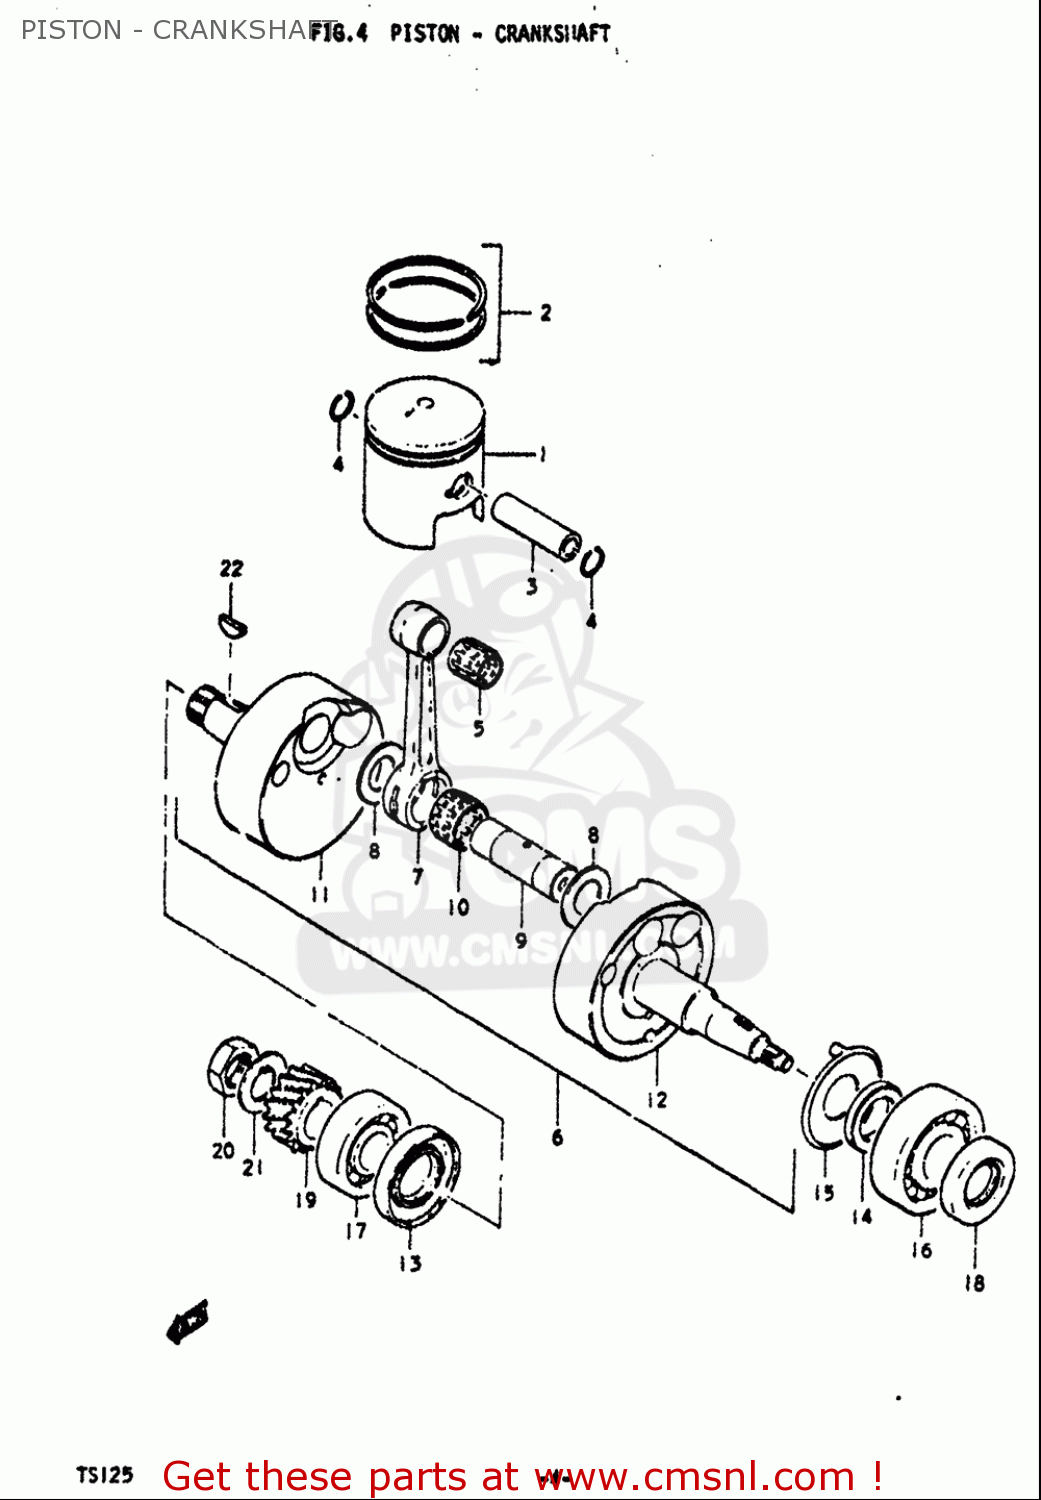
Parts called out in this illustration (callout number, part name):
1	PISTON
2	RING SET,PISTON
3	PIN ,PISTON
4	RING,SNAP 14MM
5	BEARING(14X18X19.8)
7	ROD,CONNECTING
8	WASHER(19X32X1)
9	PIN,CRANK
10	BEARING(19X25X16)
13	SEAL,OIL(26X52X8)
14	SPACER
16	BEARING(25X62X17)
17	BEARING(20X52X15)
18	SEAL,OIL(25X44X7)
20	NUT
21	WASHER
22	KEY
